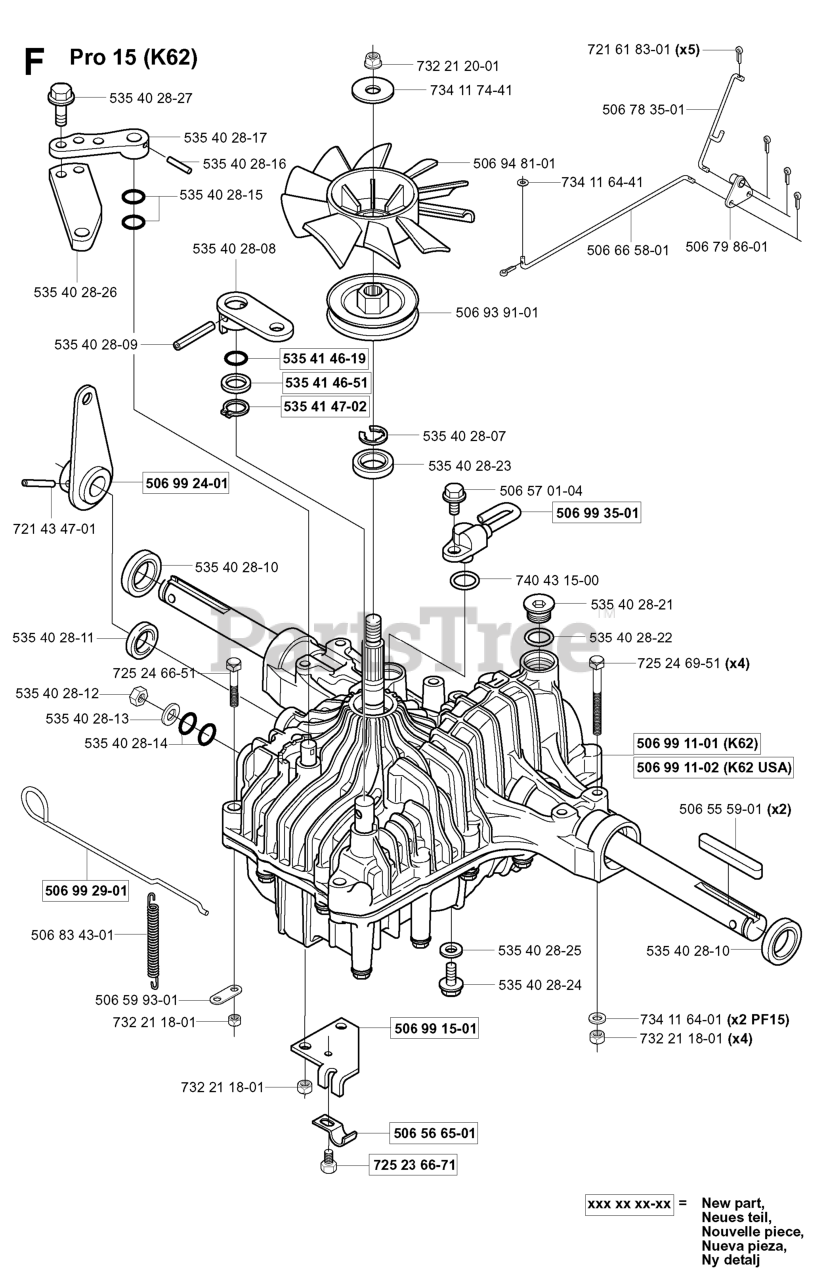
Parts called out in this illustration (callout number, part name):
1	STEERING WHEEL
2	AXLE ASM.
3	SPINDLE.ASM.LH.15"TIRES
4	SPINDLE.ASM.RH.15"TIRES
5	THRUST WASHER
9	BRNG T
10	DRAGLINK.15".TIRES.2001
11	WASHER, LOCK 3/8
12	NUT.HEX.1/2-20
13	TUBE, PIVOT AXLE
15	NUT
17	SHAFT ASM, STEERING
26	BUSHING.DRAGLINK (2 2)
28	WASHER
29	SCREW, 3/8-16X3/4
30	COTTER PIN
32	TIE ROD
36	BUSHING, STEERING
37	SCREW.TT.#10-32X.5.3/8.FLANGE
38	CAP.WHEEL.STEERING.GREY
39	Washer 9/16 ID x 1 1/2 OD 11 Ga. Zin
40	GRIPCO NUT
41	STEERING WHEEL ADAPTOR
42	BOOT STEERING
44	EXT, STEERING SHAFT
46	CAP.SPINDLE.BLACK
47	FITTING.GREASE.TAPERED
51	NUT.CROWNLOCK.1/4-28
54	Bolt Hex 1/4-28 unf x 1-1/4 Gr. 8
65	SPACER BRACE AXLE
67	BOLT CARRIAGE
68	BRACE.AXLE.15"TIRES
71	STEERING ASM
82	BRACKET
85	FASTENER.XMAS.TREE
88	BOLT, SHOULDER 7/16-20
91	CLIP.STEERING
